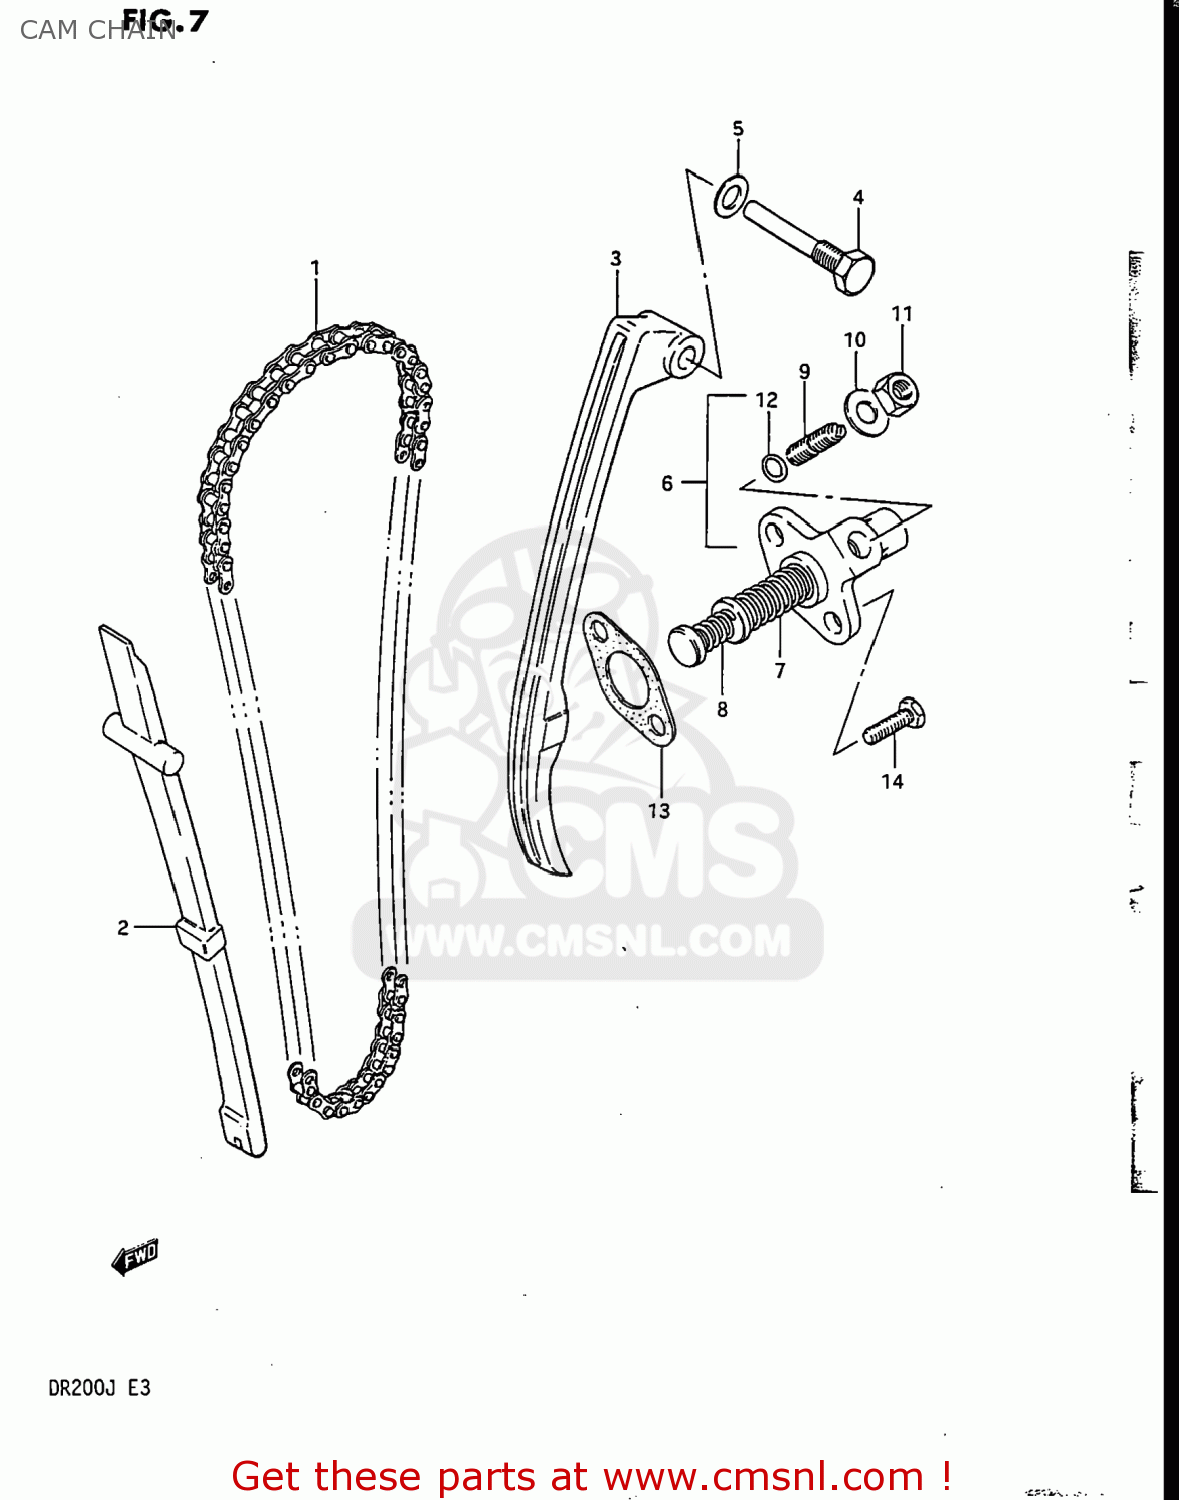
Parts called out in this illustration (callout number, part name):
1	CHAIN,CAMSHAFT DRIVE 102L
2	GUIDE,CAM CHAIN
3	TENSIONER,CAM CHAIN
4	BOLT,CAM CHAIN TENSIONER
5	GASKET 8.2X14X1 (NAS)
6	ADJUSTER ASSEMBLY,TENSIONER
7	SPRING
8	SPRING
9	SCREW
10	WASHER
11	NUT
12	O RING(D:1.9,ID:5.7)
13	GASKET,TENSIONER ADJUSTER (NAS)
14	BOLT
